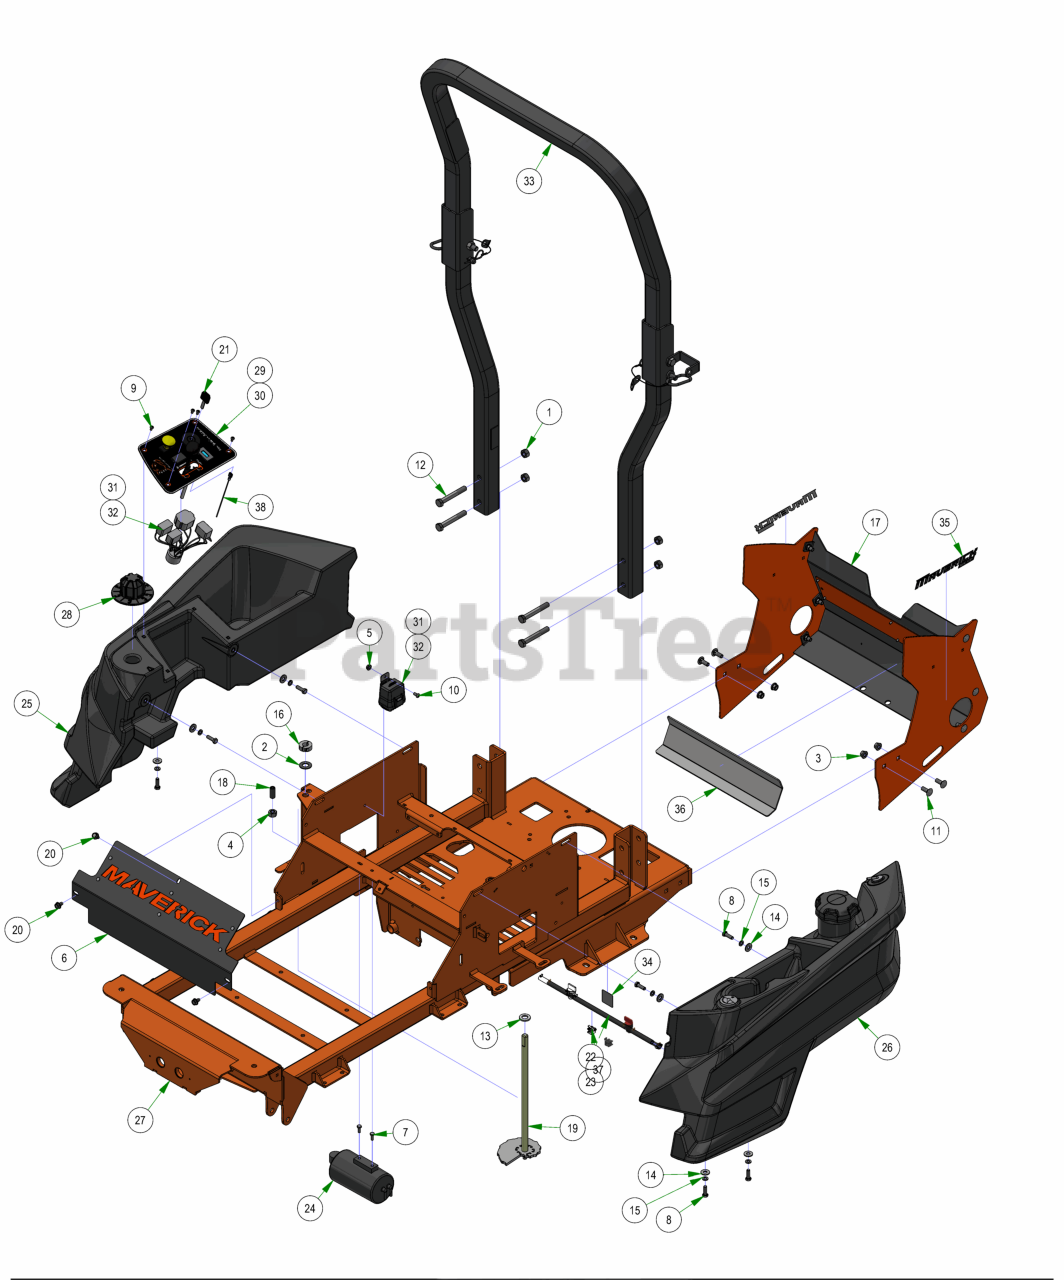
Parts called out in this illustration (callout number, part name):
1	1/2-13 HEX 2-WAY REVERSIBLE CENTER LOCKNUT Grade B ZINC
2	.625 ID x 1.250 OD x .062 THK F/W Nylon
3	3/8-16 NYLON INSERT FLANGE LOCKNUT (GR.F) ZINC
4	1/2-13 HEX NUT ZINC
5	1/4-20 HEX SERRATED FLANGE NUT HARD/ZINC
6	2021 Maverick Cooler Cover Assembly
7	M6-1.0 X 16MM DIN 933 HEX TAP BOLT (CL 8.8) ZINC
8	5/16-18 X 1 HEX CAP SCREW (GR.5) ZINC
9	10-32 X 3/8 BUTTON SOCKET CAP SCREW 18-8 STAINLESS STEEL
10	1/4-20 X 1/2 BUTTON SOCKET CAP SCREW 18-8 STAINLESS STEEL
11	3/8-16 X 1 CARRIAGE BOLT (GR.5) ZINC
12	1/2-13 X 3-1/2 HEX CAP SCREW (GR.5) ZINC
13	.635 ID X 1.120 OD X .140 THICK FLAT WASHER NYLON
14	5/16 USS FLAT WASHER (7/8 OD) ZINC
15	5/16 SPLIT LOCKWASHER ZINC
16	5/8" Split Collar
17	2022 Maverick Rear Cover Assembly
18	Dial Rod Plunger
19	ZT Deck Height Bar Assembly
20	5/16-18 X 1/2 HWH unslot (F) tcs zinc
21	Ignition Key
22	15" Fuel Line Assembly
23	37" Fuel Line Assembly
24	ZT/Mav EPA Cannister Assy
25	2021 Maverick Right Side Tank
26	2021 Maverick Left Side Tank
27	2025 Maverick Frame
28	MZ/ZT Deck Height Dial
29	2023 Control Panel Assembly
30	2025 ZT/MAV/HD Control Panel Assembly
31	2024 Wiring Harness with Clips
32	2025 Wiring Harness with Clips and Lights
33	2016 2x2 ROPS
34	Patent Decal
35	Maverick Back Plate Decal
36	Heat Shield (Fiberglass Adhesive)
37	Edge Clip With Ziptie
38	2017 MZ/ZT/MAV Tach Wire Assy
39	2 EAR CLAMP 12.5mm-15mm
